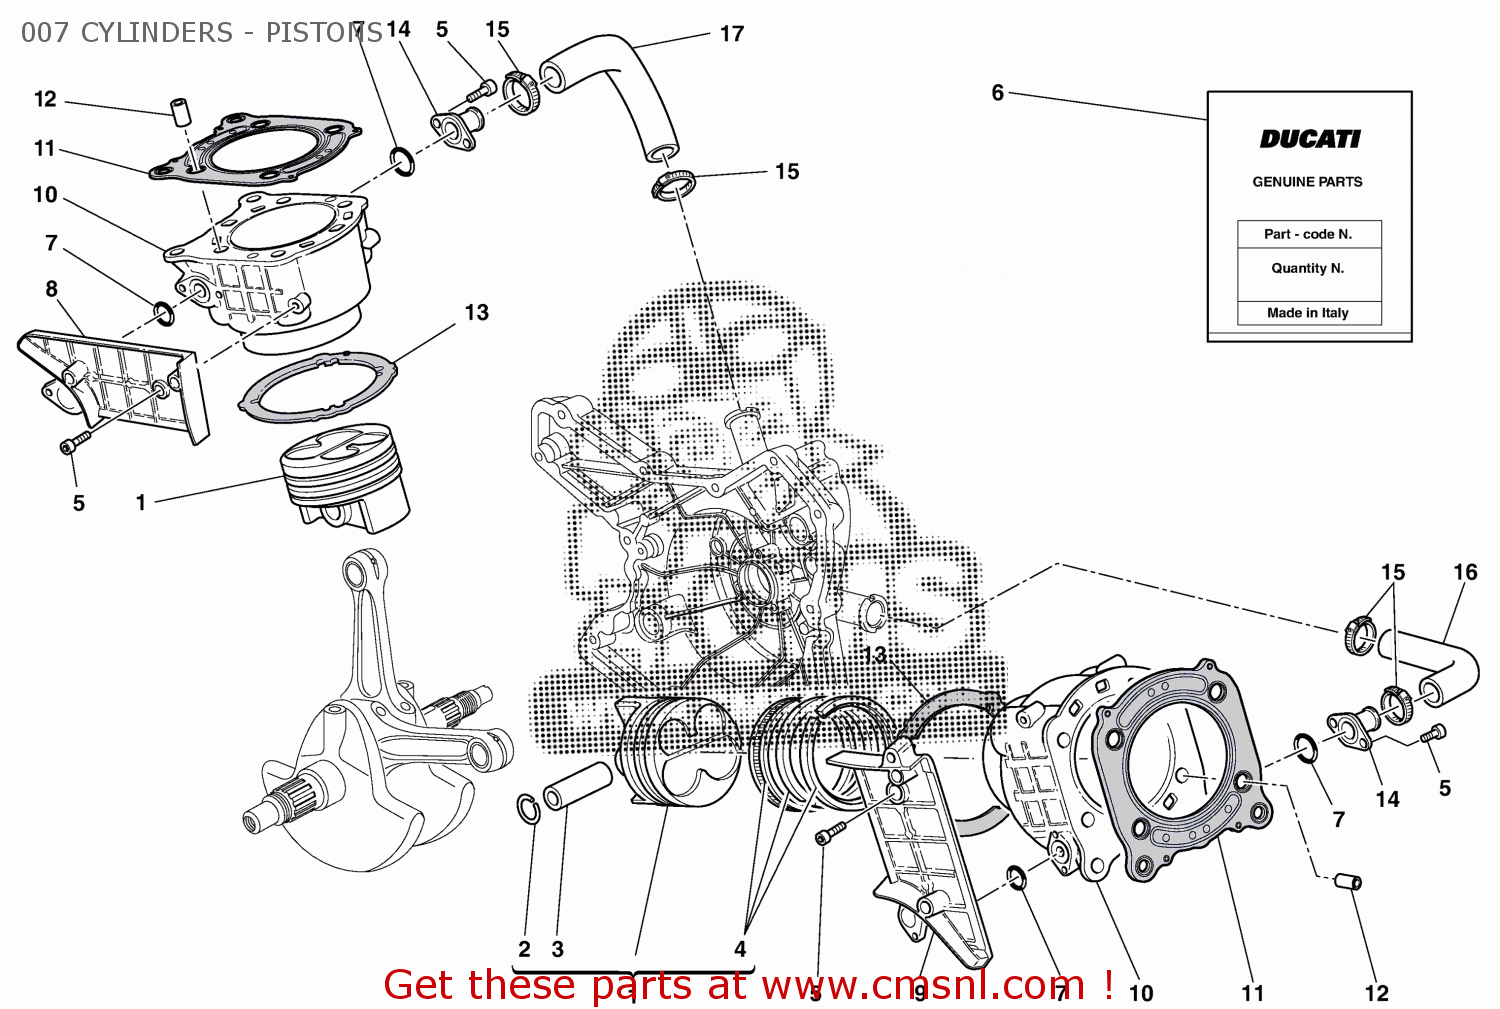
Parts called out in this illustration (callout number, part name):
1	PISTON ASSY
2	CIRCLIP, PISTON PIN
3	PISTON PIN
4	PISTON RING SET 90 MM
5	SCREW TCEI M6X16
6	GASKET SET
7	O-RING
8	COVER, TIMING BELT INSIDE
9	COVER
10	CYLINDER ASSY
11	GASKET, CYLINDER HEAD
12	PIN DOWEL
13	GASKET,CYLNDER BASE 0.4 MM
14	CYLINDER WATER INTAKE CONNECTOR
15	CLAMP
16	HORIZONTAL CYLINDER WATER INLET HOSE
17	VERTICAL CYLINDER WATER INLET HOSE
